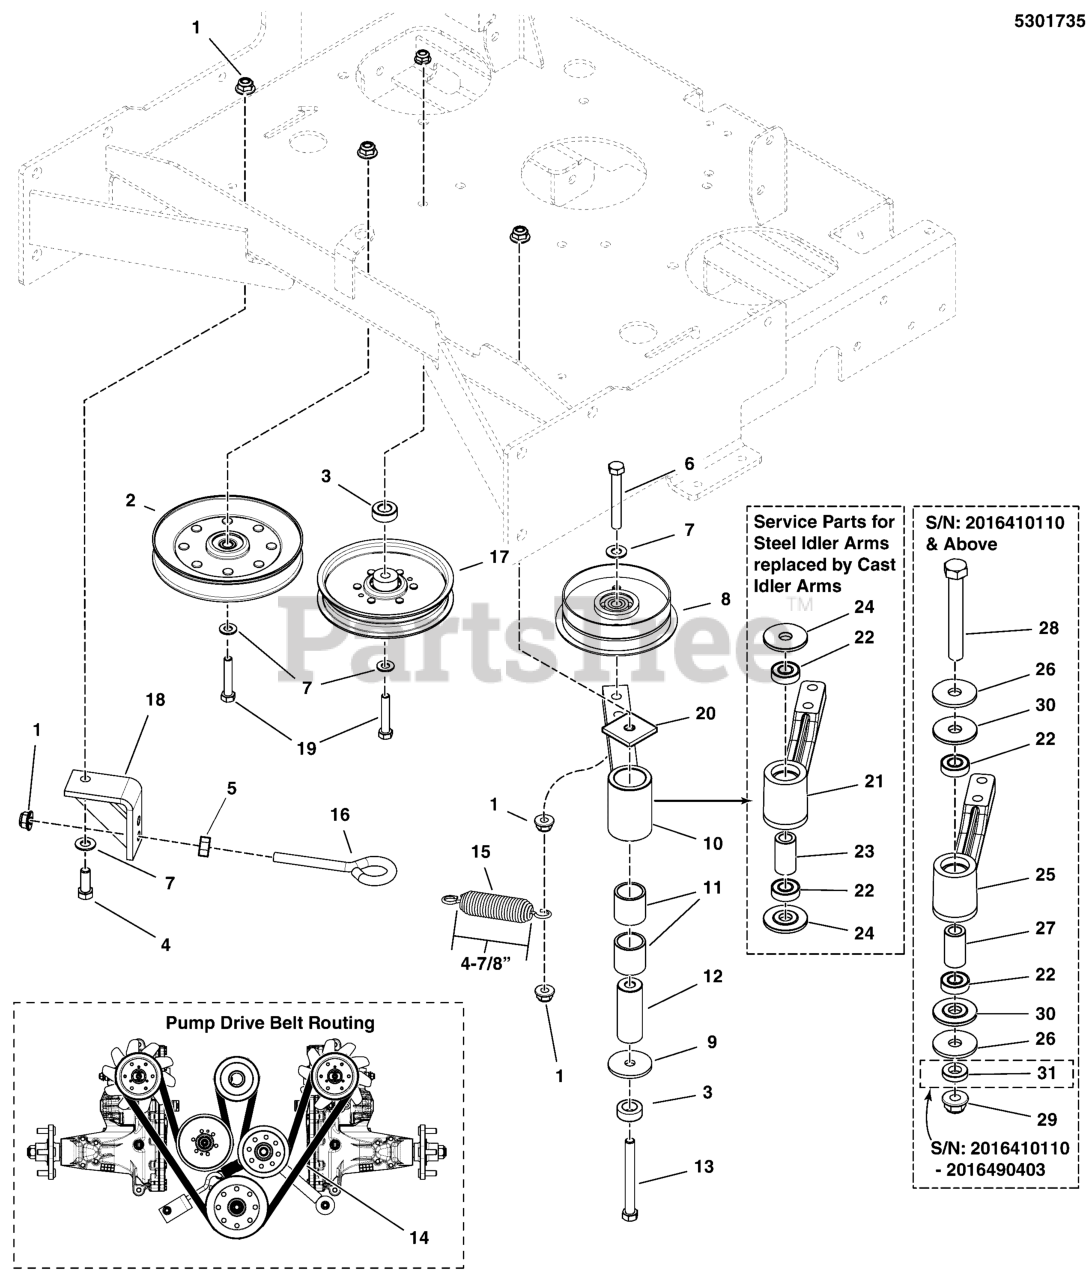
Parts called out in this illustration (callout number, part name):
1	NUT, 3/8-16 HEX NYLOCK FLANGE
2	PULLEY-IDLER-V, 5.83OB, .38ID, .94W, STL
3	SPACER, .39 X 1.00 X .25
4	BOLT, 3/8-16 X 1" GD5 CZ
5	NUT, 3/8-16 HEX JAM
6	BOLT, 3/8-16 X 2-1/2" GD5 CZ
7	WASHER, 3/8 SAE
8	PULLEY, IDLER, SINGLE FLANGE, 4" OD
9	WASHER, .41 X 1.75 X .14
11	BUSHING, BRASS, 1.25X1X1.25
12	SPACER, .39 X 1.000 X 2.55, SS
13	BOLT, 3/8-16 X 4" GD5 CZ
14	BELT, A-SEC, 100.00EL, ARAMID, WRPD
15	SPRING-EXT, 1.25 ODX5.70LGX.142WR, BLK
16	EYE BOLT, 3/8-16 X 5, 2.88THRD, 1EYE, CZ
17	PULLEY-IDLER, 5.00OD, .385ID, .75W, STL
18	WELD, ANCHOR EYEBOLT
19	BOLT, 3/8-16 X 1-3/4" GD5 CZ
20	SPACER, IDLER PIVOT
21	ASSM, IDLER ARM, PUMP DRIVE, 3/8ID, CAST
22	BEARING, BALL, AXLE
23	SPACER, .39 X .88 X 1.53, CZ
24	SPACER, IDLER ARM, T-STYLE, CZ
25	ASSM, IDLER ARM, PUMP DRIVE, 1/2ID, CAST
26	WASHER, .52 X 1.75 X .14, CZ
27	SPACER, .52 X .84 X 1.53, PM
28	BOLT, 1/2-13 X 4" GD5 CZ
29	NUT, Hex Flange, Nylock, 1/2-13
30	SPACER, IDLER ARM, 1/2, PM
31	SPACER, .52 X 1.00 X .25, CZ
